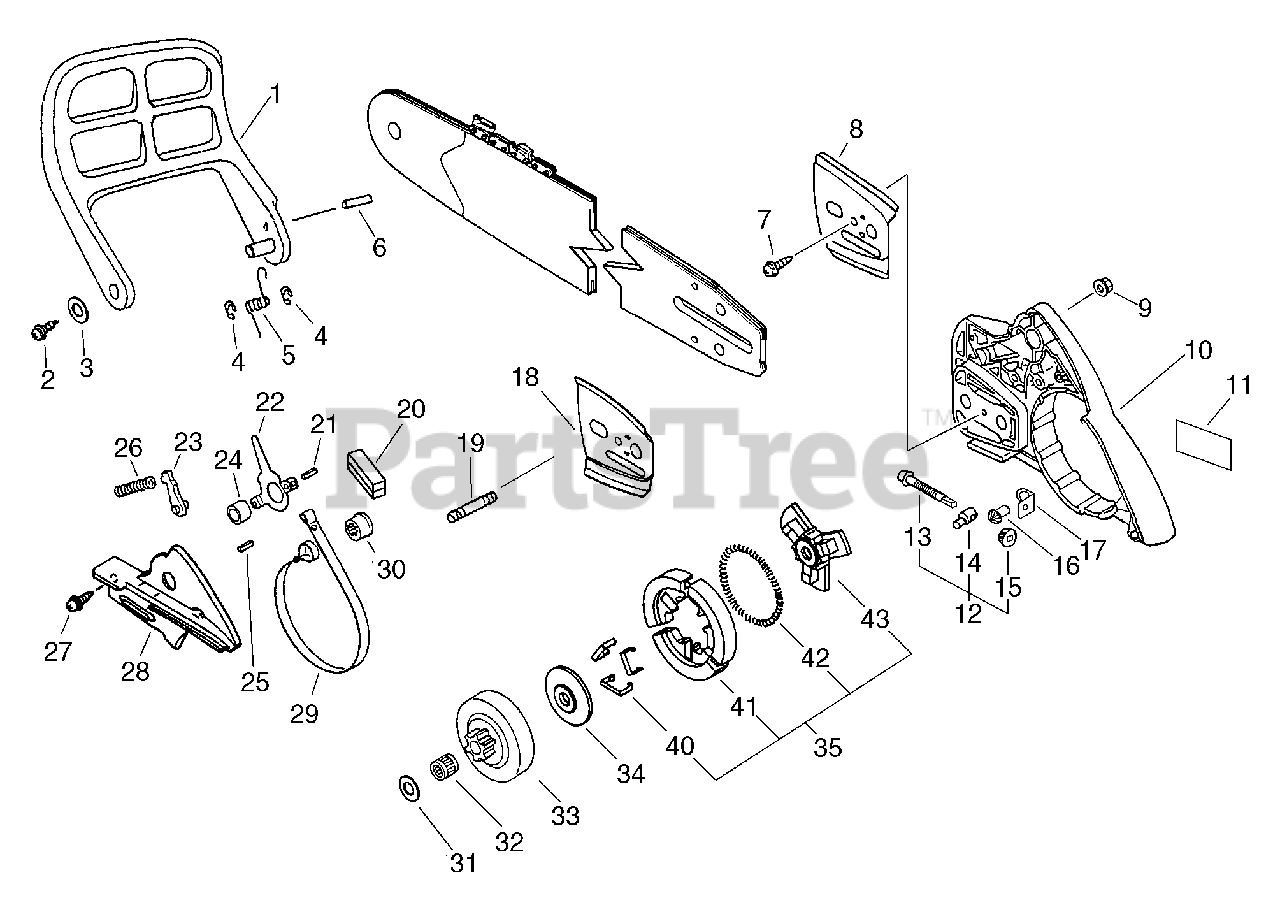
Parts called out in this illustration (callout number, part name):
1	LEVER, BRAKE
2	SCREW - 4X12 -- TAPPING
4	RING, RETAINING - 8
5	SPRING, BRAKE
6	PIN - 3X12
7	SCREW - 4X10
8	PLATE, GUIDE - INNER
9	NUT - 6 -- FLANGE
10	GUARD, SPROCKET
11	LABEL - ECHO
12	CHAIN TENSIONER ASSY
13	SCREW, TENSIONER
14	TENSIONER, CHAIN
15	GEAR - BEVEL
16	GEAR - PINION
18	PLATE, GUIDE
19	STUD, GUIDE BAR
21	PIN - SPRING -- 4X8
22	CONNECTOR, BRAKE
23	STOPPER, BRAKE
24	SPACER - 8
25	PIN - SPRING -- 2.5X12
26	SPRING, BRAKE
27	SCREW - 4X12 -- TAPPING
28	COVER, BRAKE
29	BAND, BRAKE
30	ADJUSTER, BRAKE BAND
31	WASHER
32	BEARING, NEEDLE
33	DRUM, CLUTCH
34	PLATE, CLUTCH
35	CLUTCH ASSY
40	CLIP, SPRING
41	CLUTCH SHOE SET
42	SPRING, CLUTCH
43	HUB, CLUTCH
